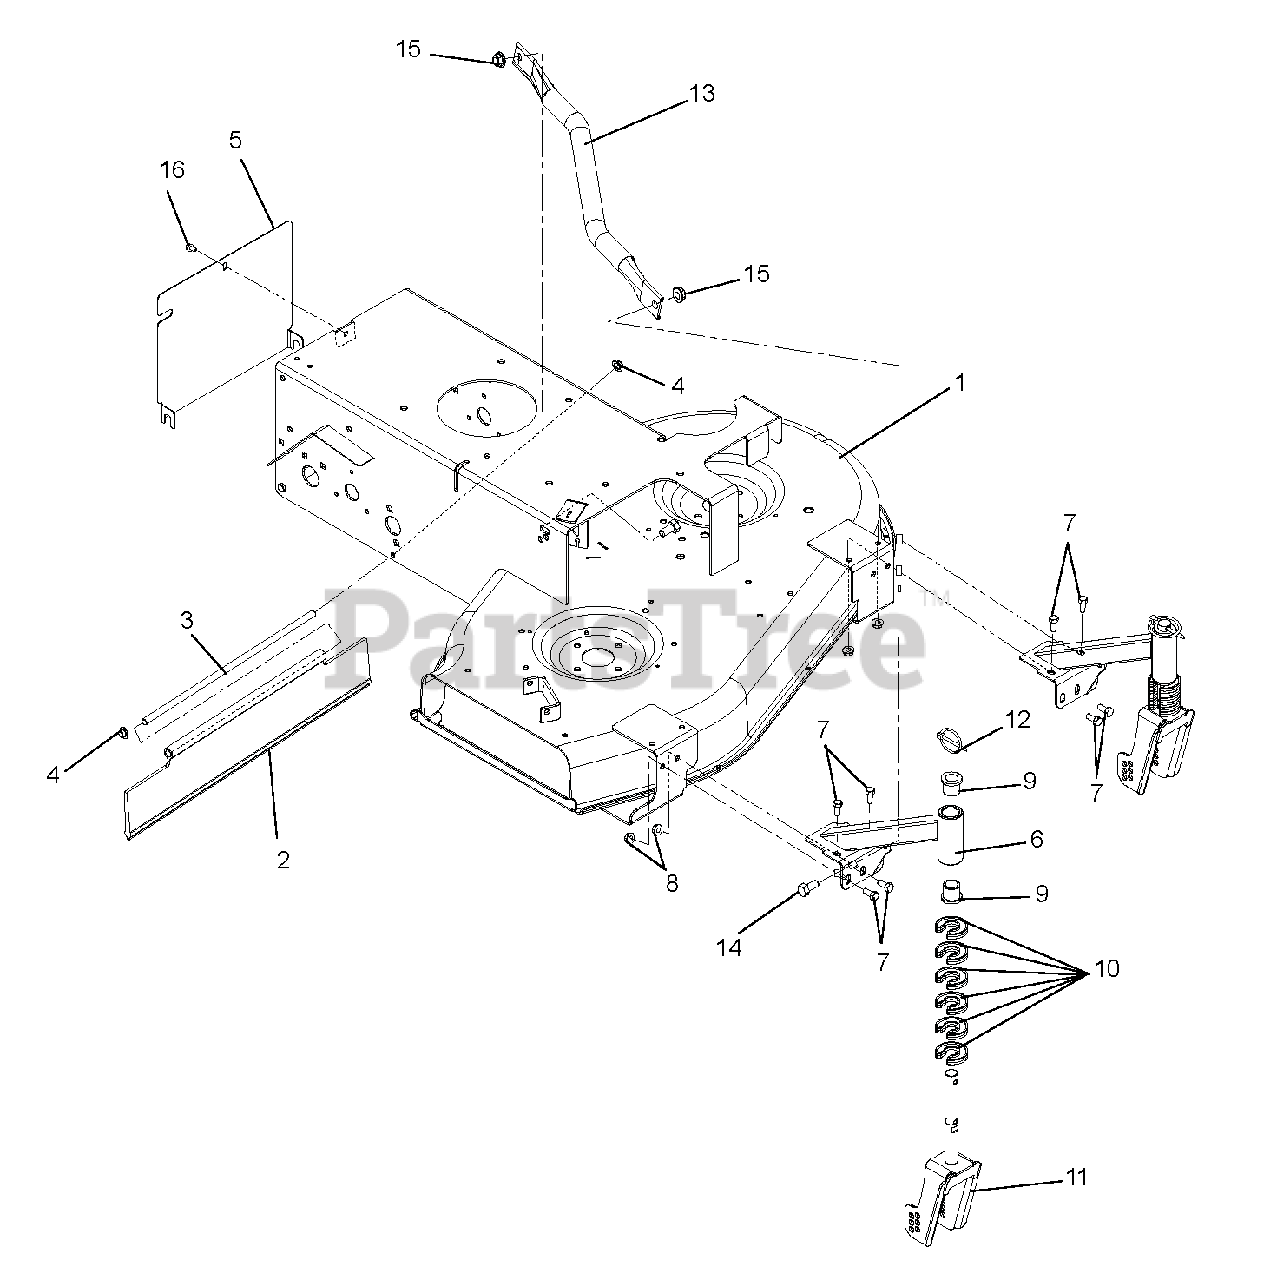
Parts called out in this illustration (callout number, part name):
1	CHASSIS, WAW 2010 (ARIENS)
2	GUARD - REAR - SWIVEL
3	ROD, TRAILING SHIELD
4	NUT-PUSH .312 DIA. PAL
5	COVER, REAR CHASSIS
6	ARM, CASTER (WLDMNT)
7	@BLT-HEX .31-18X.75 GR5 YWZC
8	@NUT-LK-TOP-FLG .31-18 YWZC
9	BUSHING, FLANGE .75X.75X1.0
10	CLIP-HOC FIXED
11	FORK, WAW CASTER (HEIGHT ADJ)
12	PIN, LYNCH - .25 X 1.25
13	TUBE-BRACE, DECK
14	@BLT-HEX .38-16X.75 GR5 YWZC
15	@NUT-LK-TOP-FLG .38-16 YWZC
16	@SCR-TAP .25-20X.50 HWH TR YWZ
